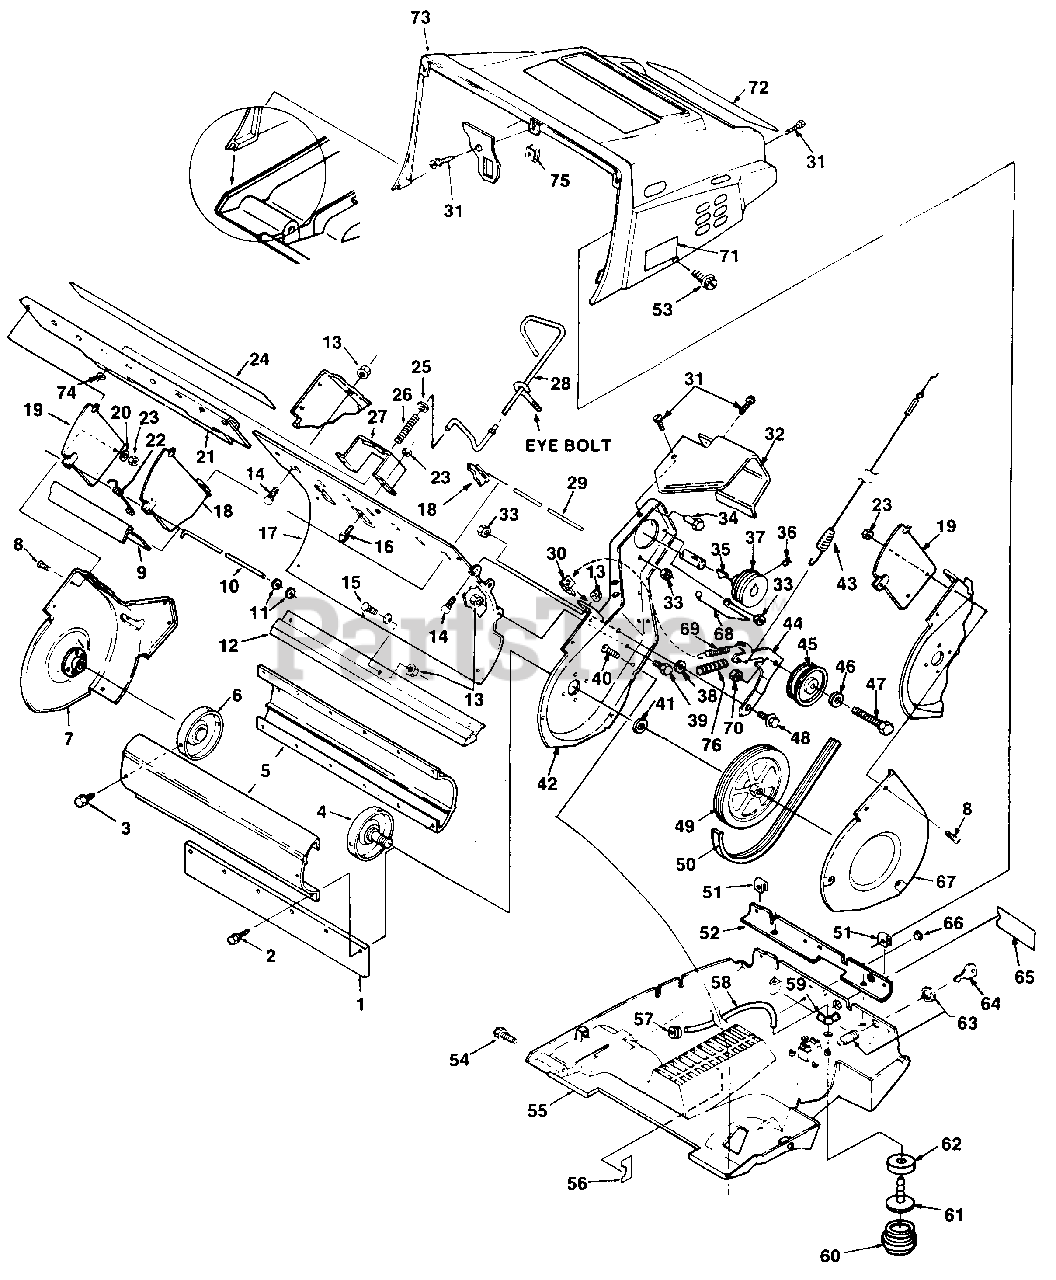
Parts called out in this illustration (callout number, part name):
1	PADDLE-Impeller
2	SCREW- 12-24 x 1"
3	SCREW- 1/4-14 x .44
4	DRIVESHAFT & PLATE KIT
5	DRUM-Impeller
6	END PLATE & PIN ASSEMBLY
7	FRAME- R.H.Side 990829
10	ROD- Retaining
12	BLADE-Scraper
13	NUT-Flange 1/4-20
14	BOLT- 1/4-20
15	BOLT- 1/4 x 3/4
16	SCREW- 10-24 x 5/8
17	HOUSING- Impeller
18	DEFLECTOR-Vane
20	WASHER-Retainer
22	SPRING-R.H.
24	DECAL-Warning
25	WASHER
28	ROD-Chute control
30	CLIP-Spring
32	SHIELD- Belt
33	NUT-Flange 5/16-18
35	KEY- 5/8 x 5/32
36	SCREW-Set
37	PULLEY-Drive
39	SCREW- 1/4-20 x 1/2
40	SCREW- 1/4-10 x 5/8
42	FRAME-Side (L.H.)
43	CABLE & SPRING
44	ARM-Idler
46	WASHER
47	SCREW- 3/8-16 x 1 1/2
49	PULLEY-Driven
50	BELT-Drive
51	NUT-Speed
52	BRACKET-Control panel
54	SCREW- 1/4-20 x 5/8
55	COWLING- Lower
56	DECAL-Fuel valve
58	FUEL LINE (Cut to 14 3/4")
59	WING NUT- 1/4-20
60	BULB-Fuel primer
61	FITTING- Fuel primer
62	CUP- Fuel primer
63	SWITCH-Ignition
64	KEY- Ignition
65	DECAL-Electric start
67	GUARD- Belt
68	GUIDE-Belt
70	NUT- Hex lock 3/8-16
71	DECAL- Heat
72	DECAL-Console
73	DECAL-320
74	COWLING-Upper
